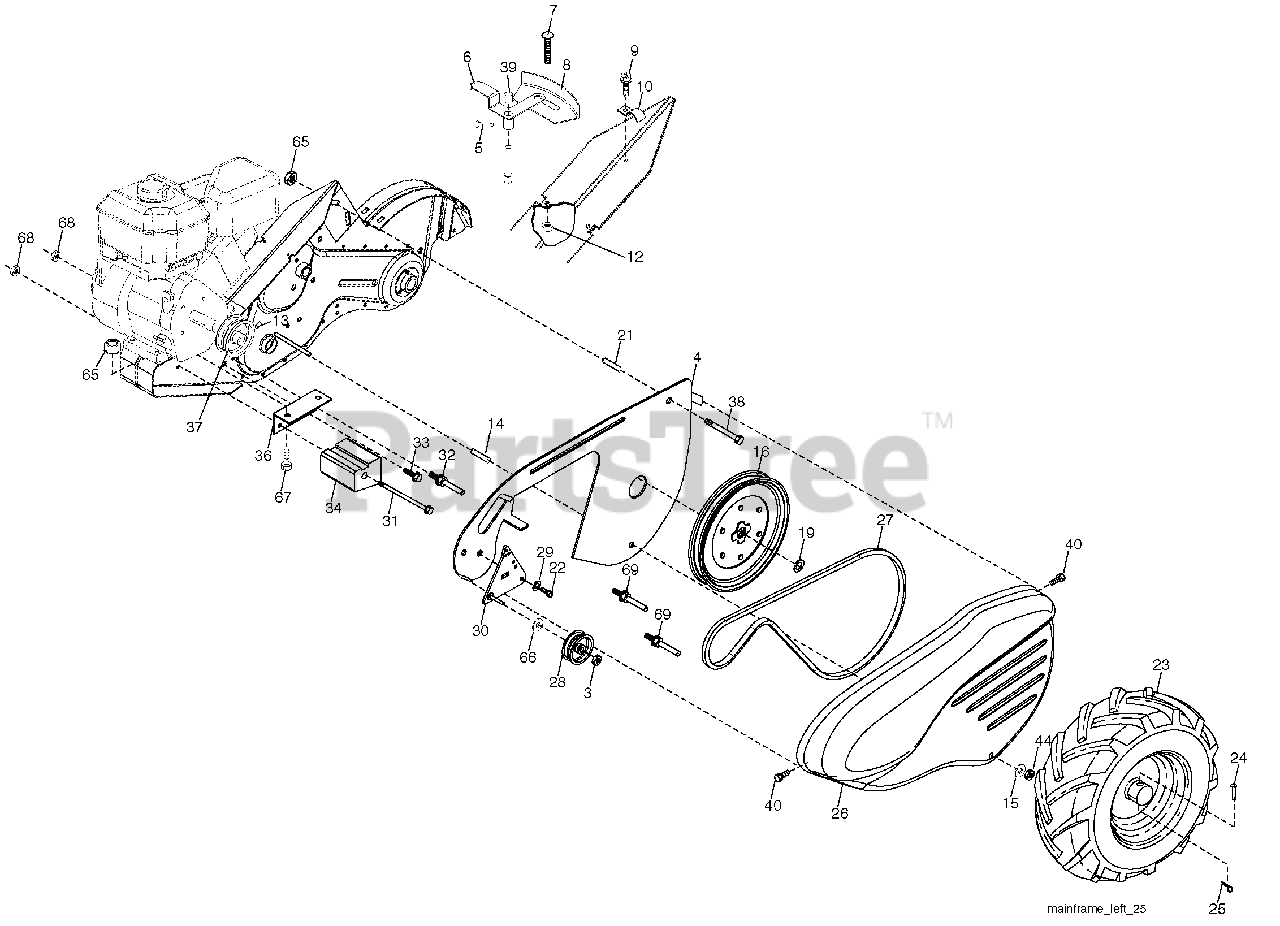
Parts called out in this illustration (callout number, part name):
3	Nut, Hex 3/8-16
4	Shield, Inner Belt Guard RT
5	Screw, Shift Lever
6	Lever, Shift
7	Bolt, Carriage 1/4-20 x 1/2 Gr. 5
8	Plate, Shift Indicator
9	Screw, Hex, Washer Head, Slotted #10-24 x 1/2
10	Clip
12	Nut, Keps Hex 1/4-20 unc
13	Screw, Set, Hex 5/16-18 x 3/8
14	Spacer, Split 0.327 x 0.42 x 1.220
15	Washer 11/32 x 11/16 x 16 Ga.
16	Sheave, Transmission
19	Retainer, Ring
21	Spacer, Split 0.327 x 0.42 x 2.09
22	Bolt, Fin Hex 5/16-24 unf x 1/2
23	Tire
23	Rim
23	Tire, Valve
24	Rivet, Drilled
25	Clip, Hairpin
26	Guard, Belt
27	Belt, V
28	Pulley, Idler
29	Ring, Klip
30	Bracket, Idler
31	Bolt, Hex 5/16-16 x 12
32	Shaft, Idler Arm
33	Bolt, Hex 3/8-16 x 1
34	Counterweight, L. H.
35	Bolt, Hex 5/16-18 x 1-3/4
36	Bracket, Reinforcement, L. H.
37	Sheave, Engine
38	Bolt, Fin Hex 5/16-18 unc x 2-3/4
39	Cap, Plunger Blk
40	Screw Hex Wsh Slt #10-24 x 1/2
44	Nut Lock Hex w/Ins 5/16-18 unc PL
65	Nut Lock Hex Flange
66	Washer 13/32 x 13/16 x 12 Ga.
68	Nut Keps Hex 3/8-16 unc
69	Keeper, Belt, Engine
